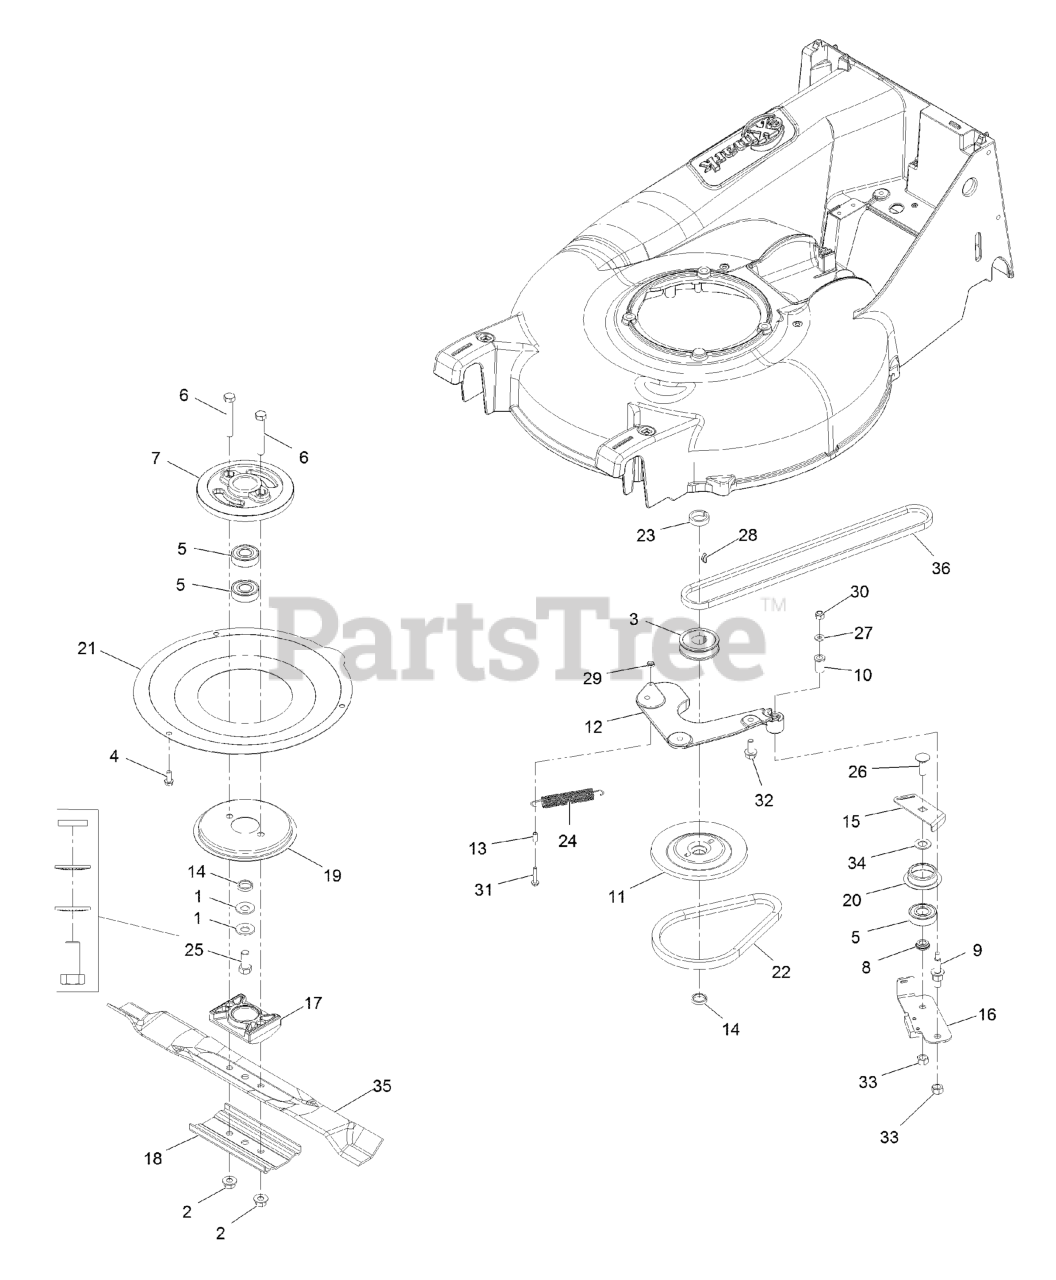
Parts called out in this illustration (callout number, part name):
1	WASHER-SPRING
2	NUT-FLANGE, LOCK
3	PULLEY-DRIVER
4	SCREW-HWH
5	BEARING-BALL
6	SCREW-HH
8	SPACER-BEARING
9	BOLT-SHOULDER
10	BUSHING
11	PULLEY-DRIVER, UPPER
12	PLATE-MOUNTING, BBC
13	SPACER-BBC
14	SPACER-PLATE, BBC
15	Plate-Guide
16	PLATE-BRAKE
17	SUPPORT-BLADE
18	SUPPORT-BLADE
20	RETAINER-BELT
21	COVER-BBC
22	BELT
23	SPACER-PULLEY
24	SPRING-EXTENSION
25	SCREW-HH
26	SCREW-CARR
27	WASHER-FLAT
28	KEY-WOODRUFF
29	NUT-LOCK, NI
30	NUT-LOCK, NI
31	SCREW-TAP
32	SCREW-HHF
33	NUT-HEX
34	SPACER
35	Blade - Medium Lift, 20.5
36	BELT,3L P21 DRIVE
